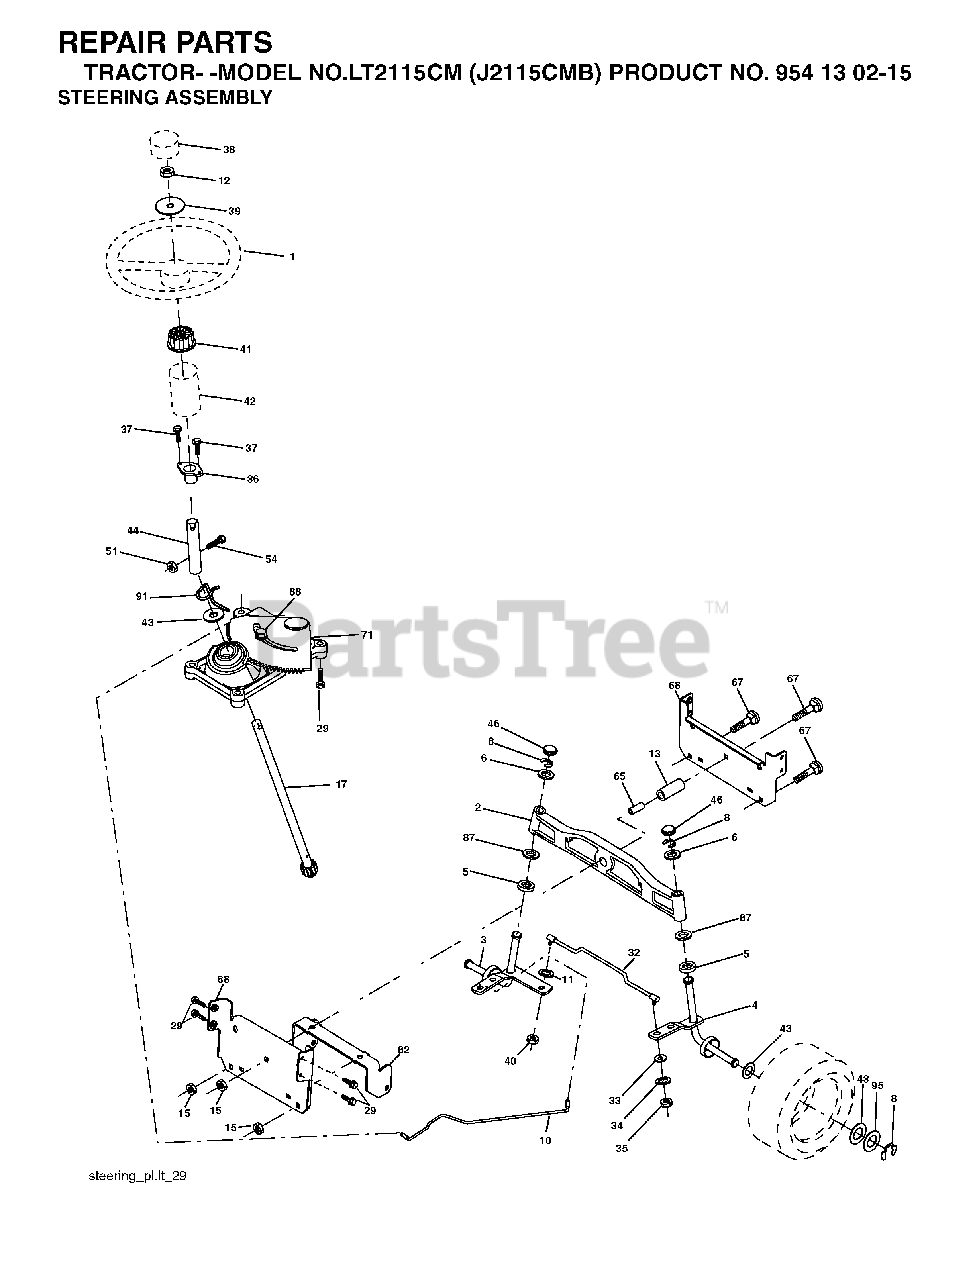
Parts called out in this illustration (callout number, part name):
2	AXLE ASSY FRONT
3	SPINDLE.ASM.LH.15"TIRES
4	SPINDLE.ASM.RH.15"TIRES
8	RING CLIP
10	DRAGLINK.15".TIRES.2001
11	WASHER, LOCK 3/8
12	NUT.HEX.1/2-20
13	TUBE, PIVOT AXLE
15	NUT
17	SHAFT ASM, STEERING
29	SCREW, 3/8-16X3/4
32	ROD.ASM.TIE.BALL.JOINT.NOVAN
33	WASHER M
34	LOCKWASHER
35	NUT, CROWNLOCK
36	BUSHING, STEERING
40	NUT CROWNLOCK 3/8-24
41	STEERING WHEEL ADAPTOR
42	BOOT.STEERING.SHAFT.BLACK
44	EXT, STEERING SHAFT
46	CAP.SPINDLE
51	CROWN LOCKNUT
65	SPACER BRACE AXLE
67	BOLT CARRIAGE
68	BRACE.AXLE.15"TIRES
71	STEERING ASM
82	BRACKET
87	WASHER, FLAT .781 X 1 1/2"
88	BOLT, SHOULDER 7/16-20
91	CLIP.STEERING
95	WASHER.HARDENED
